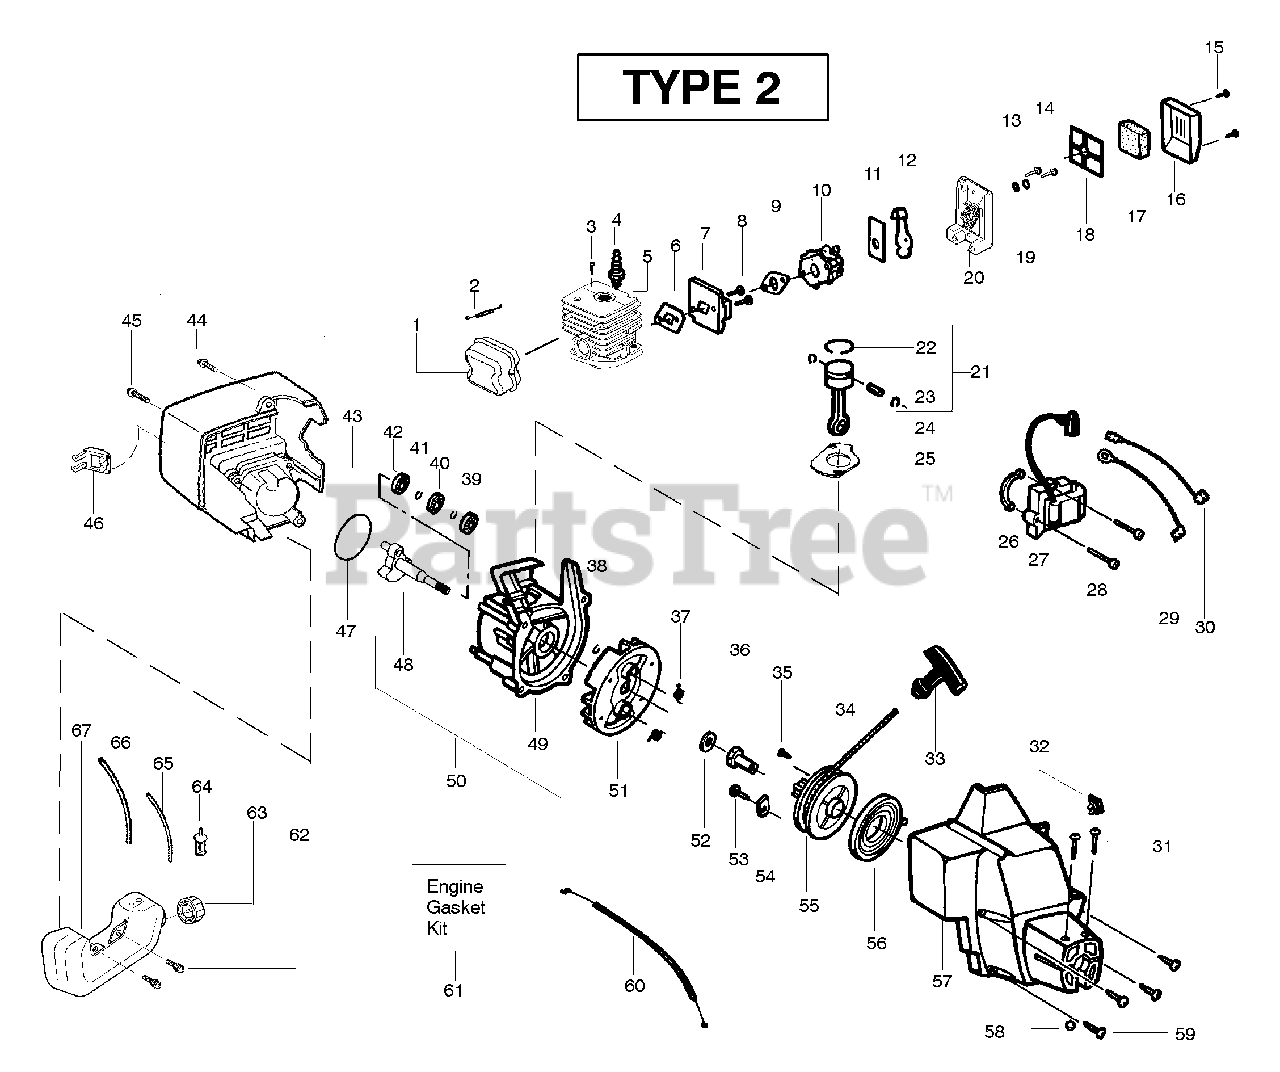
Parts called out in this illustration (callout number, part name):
1	Kit - Muffler
2	Muffler Spring
3	Screw-Cylinder
4	Spark Plug (RCJ 6Y)
5	Kit - Cylinder
6	Gasket-Cyl/Carb.(kit)
7	Adaptor-carb.
9	Gasket-Carb.(kit)
10	Kit-Carb. (WA226)
11	Plate-Choke Mounting
12	Lever-Choke
16	Cover-Air Box
17	Foam-Air Filter
18	Plate-Air Filter Support
19	Spacer-Choke
21	Kit - Piston
22	Piston Ring
23	Retainer-Piston Pin
24	Assy-Connecting Rod
25	Gasket-Cylinder(kit)
26	Spacer-Module
27	Ignition Module
29	Assy-Ground Wire
30	Assy-Leadwire
32	Kit-Switch
33	Handle-Starter
34	Kit - Rope
36	Coupling-Drive
37	Spring-Starter Dog
38	Retain. Ring-C'shaft
39	Bearing-Outer
40	Seal-C'case
41	Retainer Ring-C'case
42	Bearing-Inner
45	Screw
46	Guard-Muffler
47	O-Ring-C'case(kit)
48	Assy-Crankshaft
49	Assy-Crankcase
50	Assy-C'case & C'shaft
51	Assy-Flywheel
52	Washer-Flat
54	Retainer-Pulley
55	Kit-Starter Pulley
56	Spring-Starter
57	Assy-Fan Housing
59	Screw
60	Kit-Throttle Cable
61	Kit-Engine Gasket
62	Retainer-Fuel Tank
63	Assy-Fuel Cap
64	Assy-Fuel Pickup
65	Kit-Fuel Line
66	Kit-Fuel Line
67	Assy-Fuel Tank
